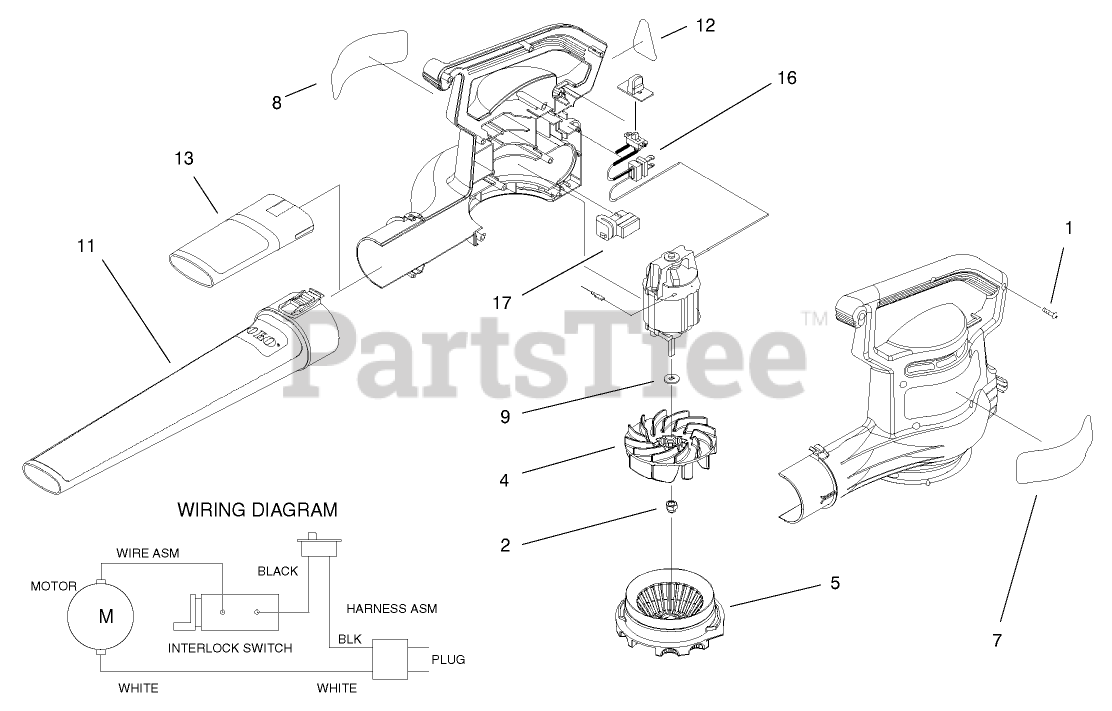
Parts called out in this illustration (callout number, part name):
1	SCREW-PPH
2	NUT-HEX
4	IMPELLER - BLOWER
5	INLET COVER & DECAL ASM
7	DECAL-LOGO
8	DECAL - WARNING
9	WASHER
11	TUBE-BLOWER LONG
12	DECAL - INFORMATION
13	INSERT - TUBE
16	WIRE HARNESS
17	SWITCH - INTERLOCK
